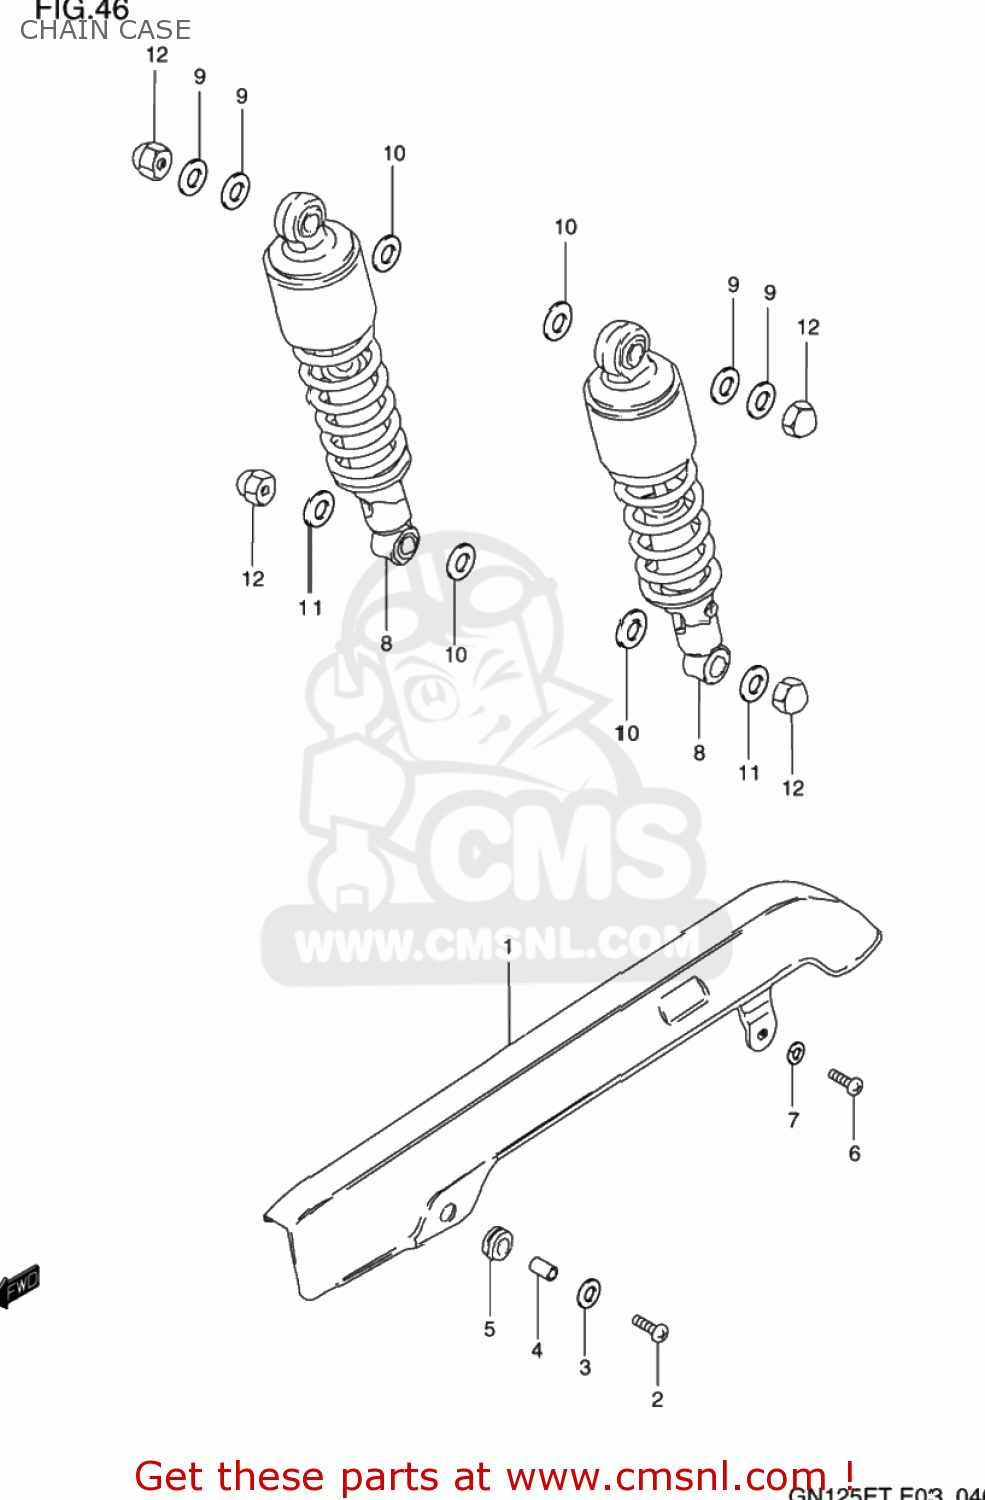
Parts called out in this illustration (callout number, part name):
1	CASE,CHAIN
2	SCREW
3	WASHER (6.5X20X1.2)
4	SPACER (7X9X7)
5	CUSHION
6	SCREW
7	WASHER,LOCK
8	ABSORBER ASSY,RR SHOCK
9	WASHER
10	WASHER (12.5X27X1.6)
11	WASHER
12	NUT
